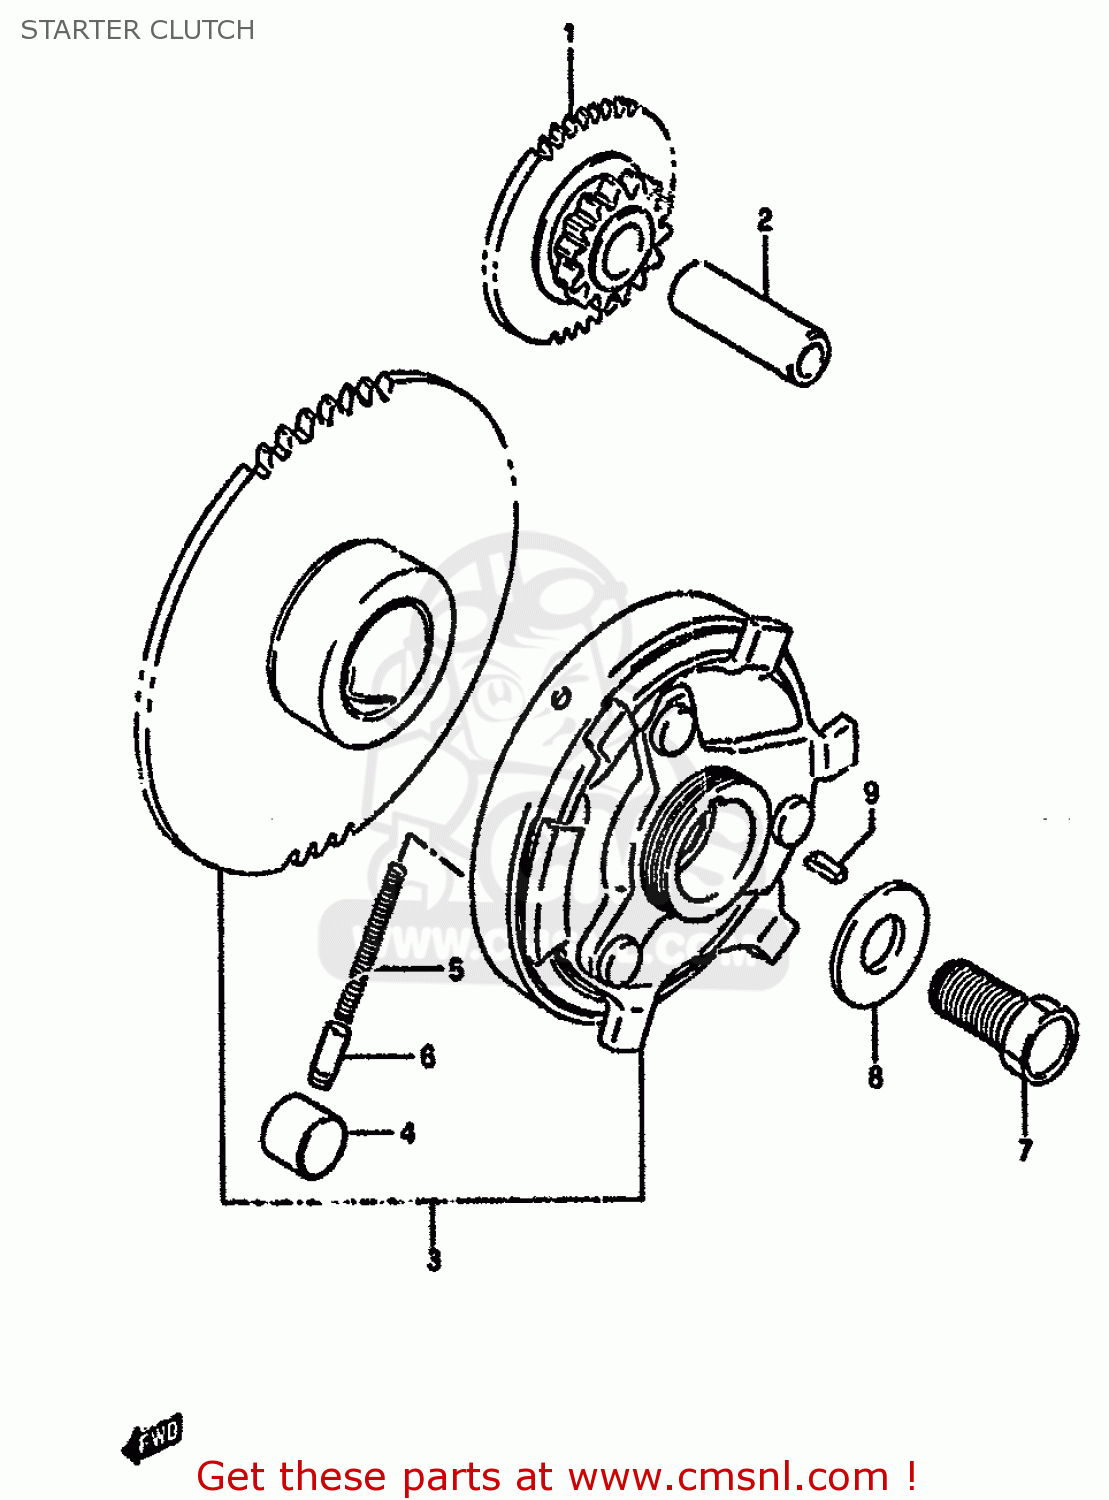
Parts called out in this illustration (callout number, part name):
1	GEAR,STARTER IDLE
2	PIN(7.4X13X40)
3	CLUTCH SET,STARTER
4	ROLLER(15X13)
5	SPRING
6	PIECE,PUSH
7	BOLT
8	WASHER(12X30X3)
9	KEY
